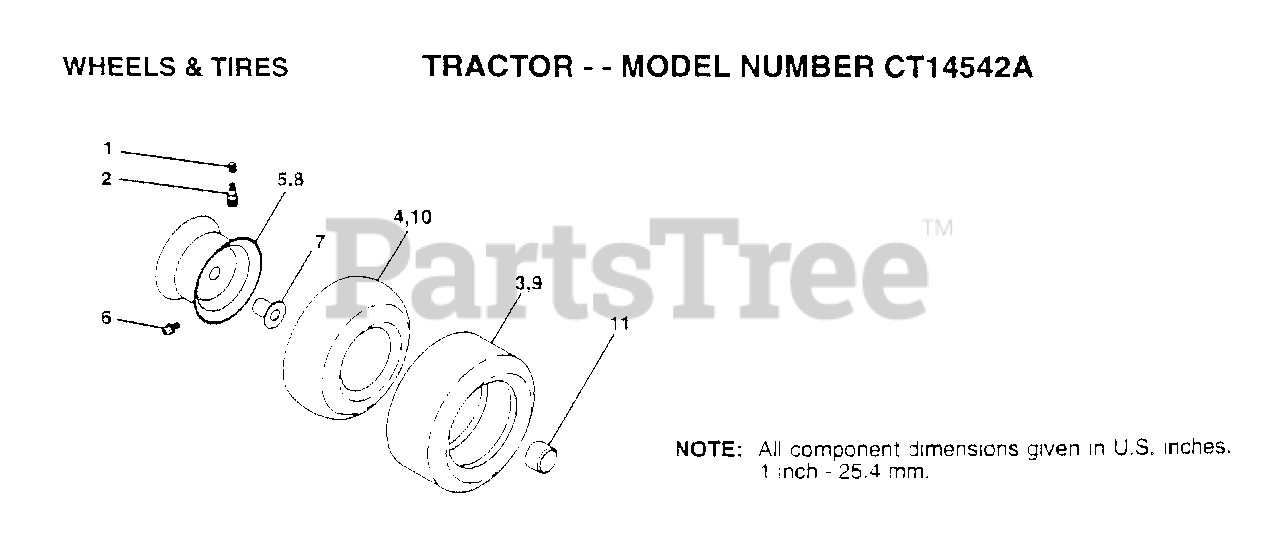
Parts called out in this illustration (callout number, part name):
1	VALVE CAP
2	VALVE STEM LT
4	TUBE.5.3/4.5/6
5	"RIM.ASM.6""FRONT"
6	FITTING LT
7	"FLANGE, BEARING"
8	"RIM.ASM.8""REAR"
10	TUBE.18X9.5-8
11	HUB CAP
